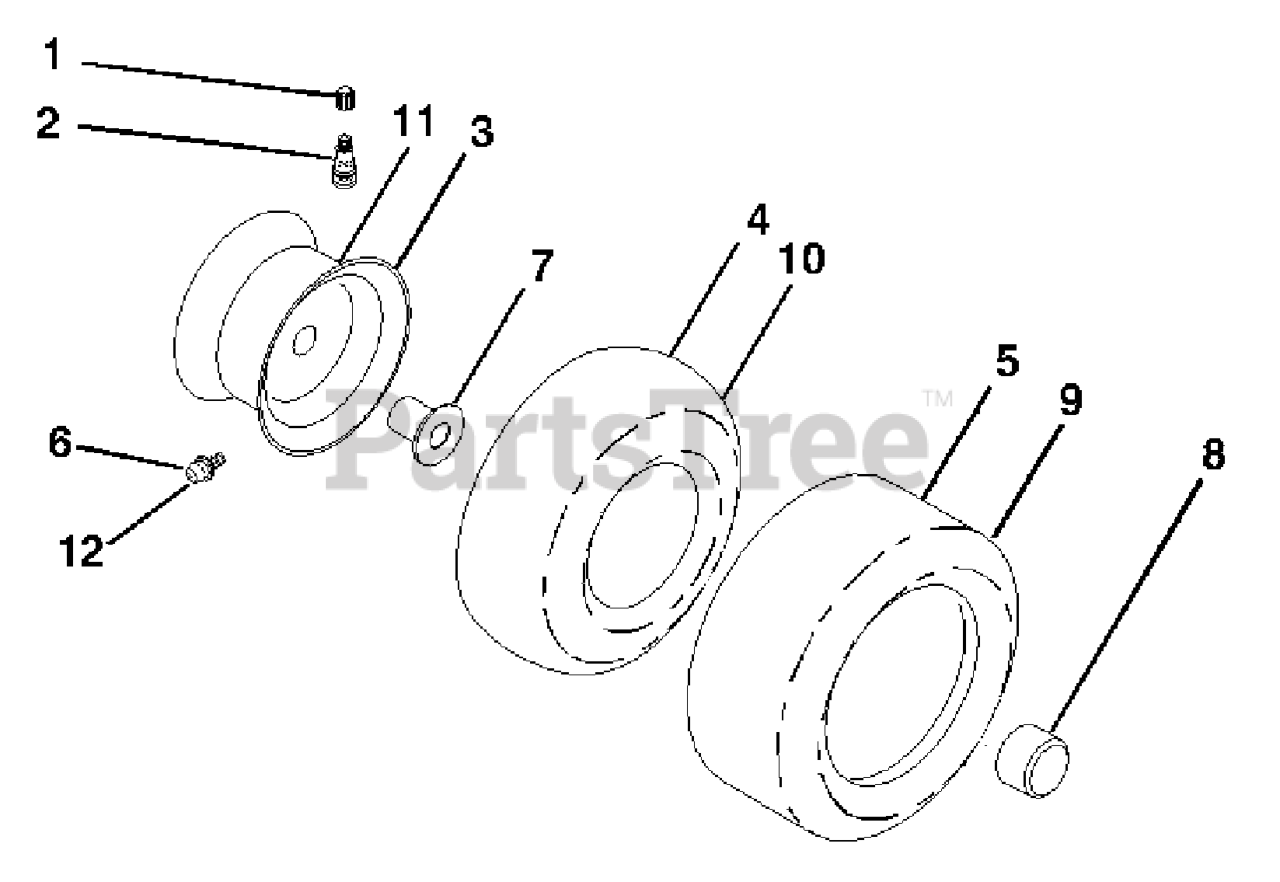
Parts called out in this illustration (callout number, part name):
2	VALVE STEM LT
3	RIM ASSEMBLY, FRONT
4	TUBE.16X6.5/7.5-8
5	TIRE HEAVY DUTY
6	FITTING LT
7	BEARING T
8	CAP, AXLE BLK
9	TIRE HEAVY DUTY
10	TUBE.23X9.5-12
11	RIM.ASM.12X7.REAR.SILVER
12	ZERK FITTING M
